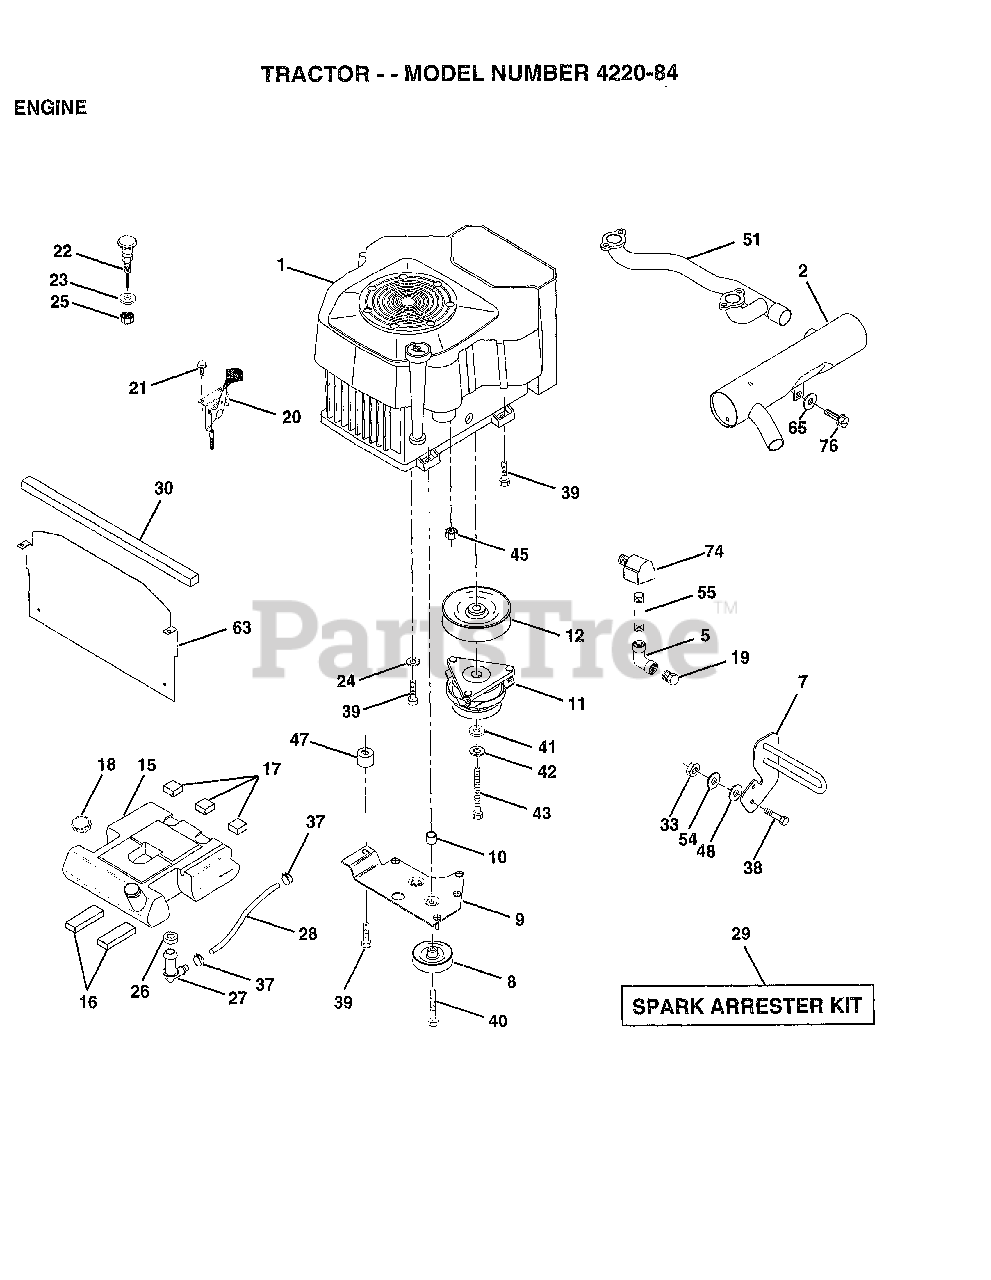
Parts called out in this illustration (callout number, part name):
2	MUFFLER SIDE1-1/8
5	ELBOW
7	GUARD.MUFFLER.ASM
9	KEEPER ASM BELT
10	BUSHING.
12	PULLEY.ENG.CLUTCH
15	TANK FUEL REAR
16	PAD IDLER TI
17	PAD-SPACER LT
18	CAP ASM FUEL
19	PLUG T
21	SCREW LT
22	CHOKE CONTROL
23	WASHER
24	LOCKWASHER
25	"NUT,KEPS 3/8-24IM"
26	BUSHING OUTLET T
27	STEM.TANK.FUEL
29	SPARK ARREST KIT
30	FOAM-STRIP LT
33	NUT
37	HOSE CLAMP
38	"BOLT,HEX"
39	SCREW.3/8-16X2.25
40	SCREW.TT.3/8-16X4
41	WASHER
42	LOCKWASHER
43	BOLT.7/16-20X4.25
45	NUT
47	SPACER.ENGINE
48	WASHER T
51	MANIFOLD PIPE VGT
54	WASHER
55	PIPE NIPPLE LT
63	HEAT.SHIELD.VGT.
65	WASHER
74	ELBOW STREET BASS
76	SCREW
